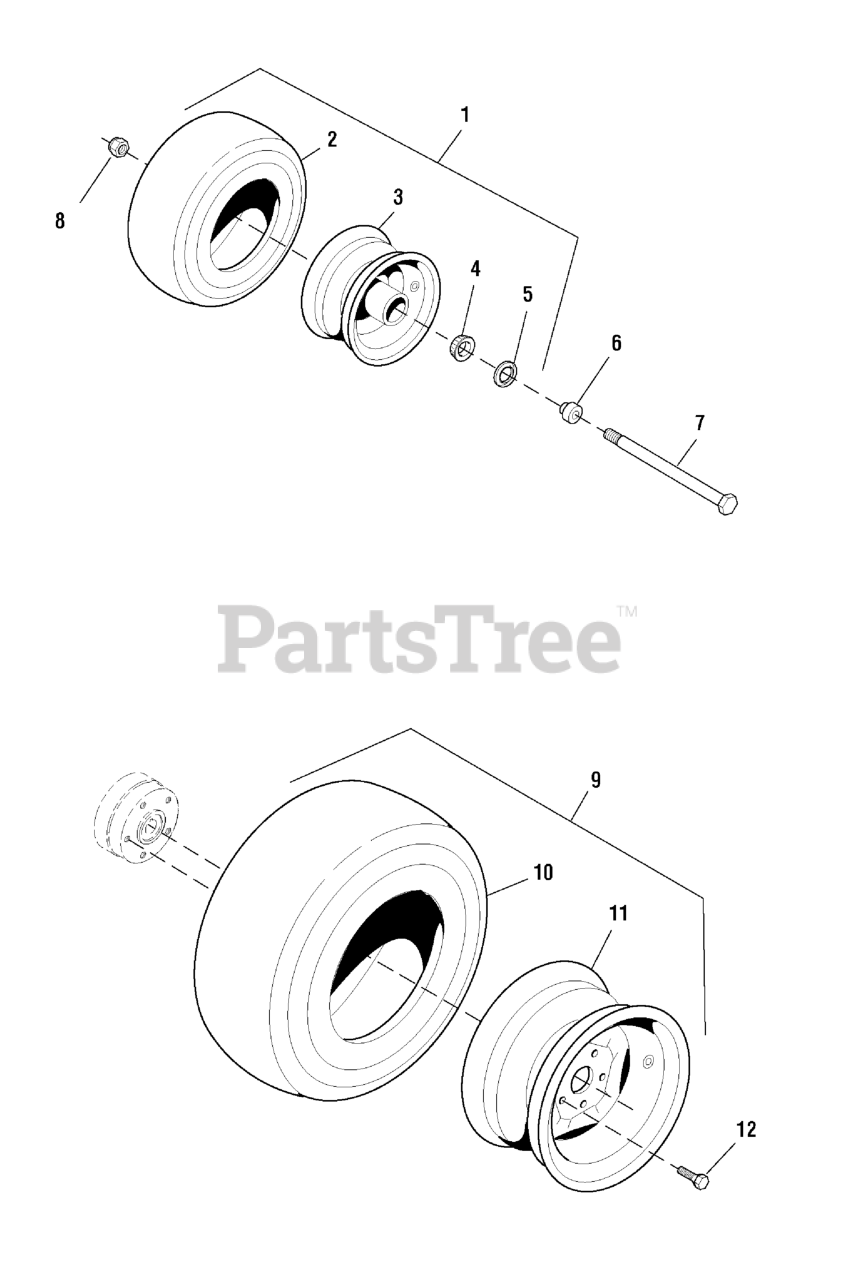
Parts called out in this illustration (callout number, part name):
1	TIRE ASSM, 13 X 6.5 - 6, PNE / TB
2	TIRE, RUBBER ONLY
3	WHEEL ASSEMBLY, for 13 x 6.5 x 6 Tires, Complete
4	BEARING, Tapered Roller
5	SEAL, GREASE
6	ADAPTER, CASTER AXLE, CZ
7	BOLT, 1/2-13 x 9
8	NUT, 1/2-13 HEX NYLON LOCK
9	WHEEL & TIRE ASSEMBLY, 23 x 10.5 x 12, Complete
10	TIRE, Rear, 23 x 10.5 x 12
11	WHEEL ASSEMBLY, for 23 x 10.5 x 12 Tires
12	WHEEL LUG, 1/2 x 1-5/8
